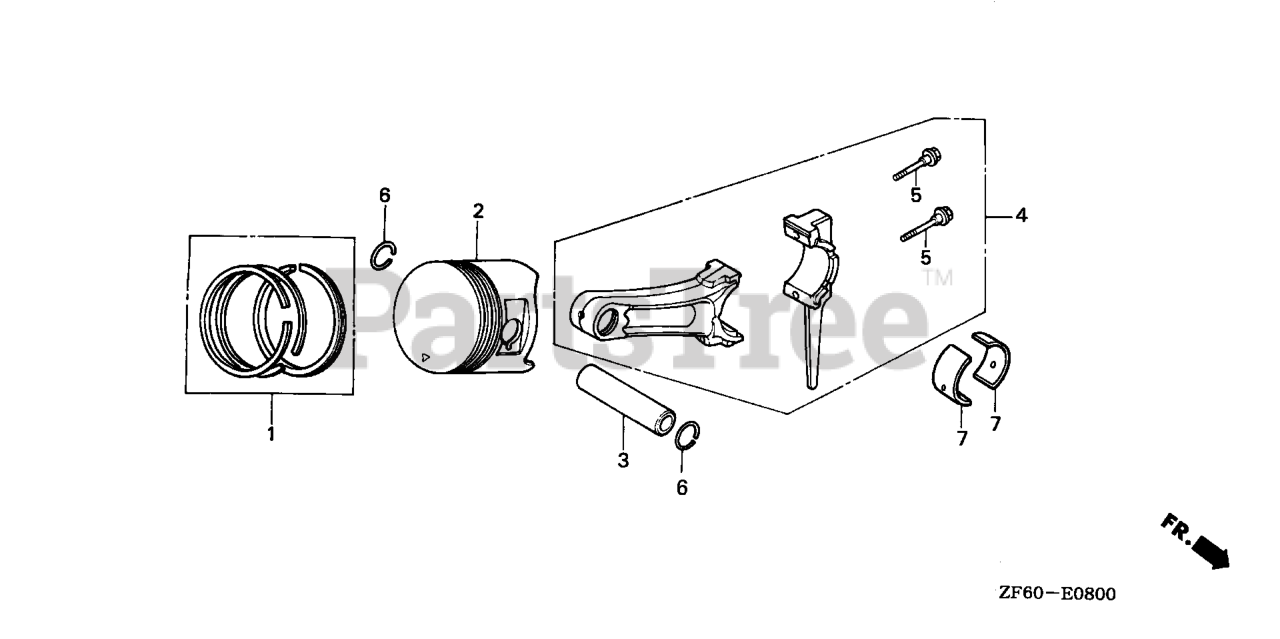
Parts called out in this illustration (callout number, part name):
1	RING SET, PISTON (STD)
1	RING SET, PISTON (OS 0.25)
1	RING SET, PISTON (OS 0.50)
1	RING SET, PISTON (0.75) (NIPPON)
2	PISTON (STD)
2	PISTON (OS 0.25)
2	PISTON (OS 0.50)
2	PISTON (OS 0.75)
3	PIN, PISTON
4	ROD ASSY., CONNECTING (US 0.25)
4	ROD ASSY., CONNECTING (STD)
5	BOLT, CONNECTING ROD
6	CLIP, PISTON PIN (20MM)
